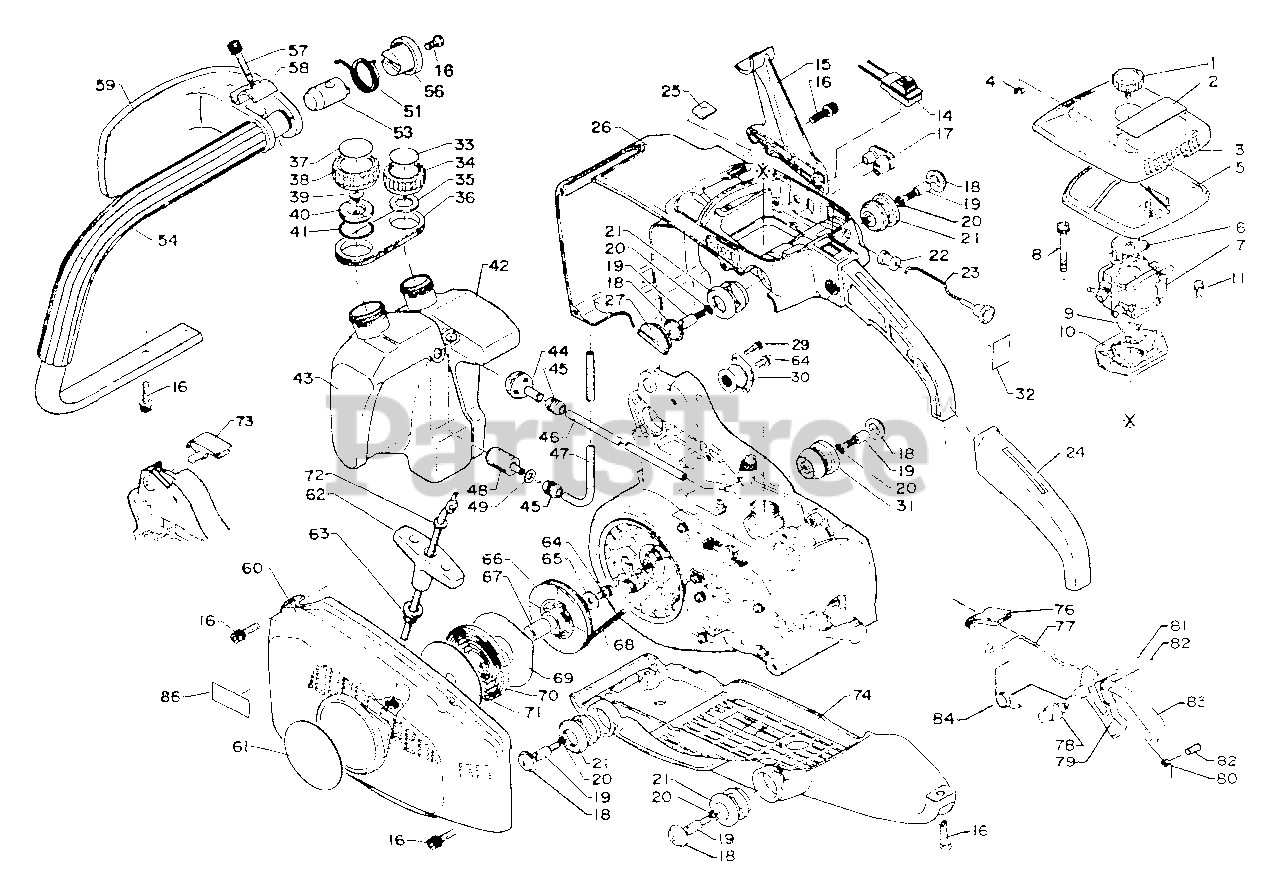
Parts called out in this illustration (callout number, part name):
1	THUMBSCREW
2	LABEL, MODEL
3	COVER, AIR FILTER
4	O-RING 3
5	FILTER, AIR
6	BRACKET, AIR FILTER
7	CARBURETOR - HDB-11B
8	SCREW 5×45
9	HOLDER
10	ADAPTER
11	SCREW 4×12
14	SWITCH, IGNITION
15	BRACKET, HANDLE - UPPER
16	BOLT 5×20
17	GROMMET
18	CAP, CUSHION
20	WASHER, SPRING 5
21	CUSHION
22	GROMMET, CHOKE
23	ROD, CHOKE
24	GRIP, HANDLE
26	HANDLE - REAR
27	COVER, CUSHION
29	BOLT 4×10
30	CUSHION
31	CUSHION
32	LABEL
33	LABEL - CHAIN OIL
34	CAP ASSY
35	GASKET, CAP
36	CONNECTOR
37	LABEL - FUEL MIX
38	CAP ASSY
39	VALVE, CHECK
40	HOLDER, CHECK VALVE
41	O-RING 22
42	TANK, OIL
43	TANK, FUEL
44	FILTER, OIL
46	PIPE, OIL
47	PIPE
48	FILTER, FUEL
49	WASHER 5.5×12×0.8
53	SPACER, HANDLE
54	HANDLE, FRONT
56	RETAINER
57	BOLT M5×35
58	STOPPER
59	GUARD
60	CASE, STARTER
61	LABEL
63	GUIDE, ROPE
64	SCREW 5×10
65	WASHER 5.2×16×1.0
66	REEL, ROPE
68	ROPE, STARTER
69	PLATE, SIDE
70	SPRING, RECOIL
71	PLATE, STARTER
73	COVER
74	SUPPORT
76	GROMMET
77	ROD, THROTTLE
78	LATCH, THROTTLE
79	TRIGGER, THROTTLE
80	SPRING, LOCKOUT RETURN
81	PIN, SPRING 5×25
82	PIN, SPRING 4×13
83	LOCKOUT, THROTTLE
84	SPRING, THROTTLE RETURN
86	LABEL - NOISE
